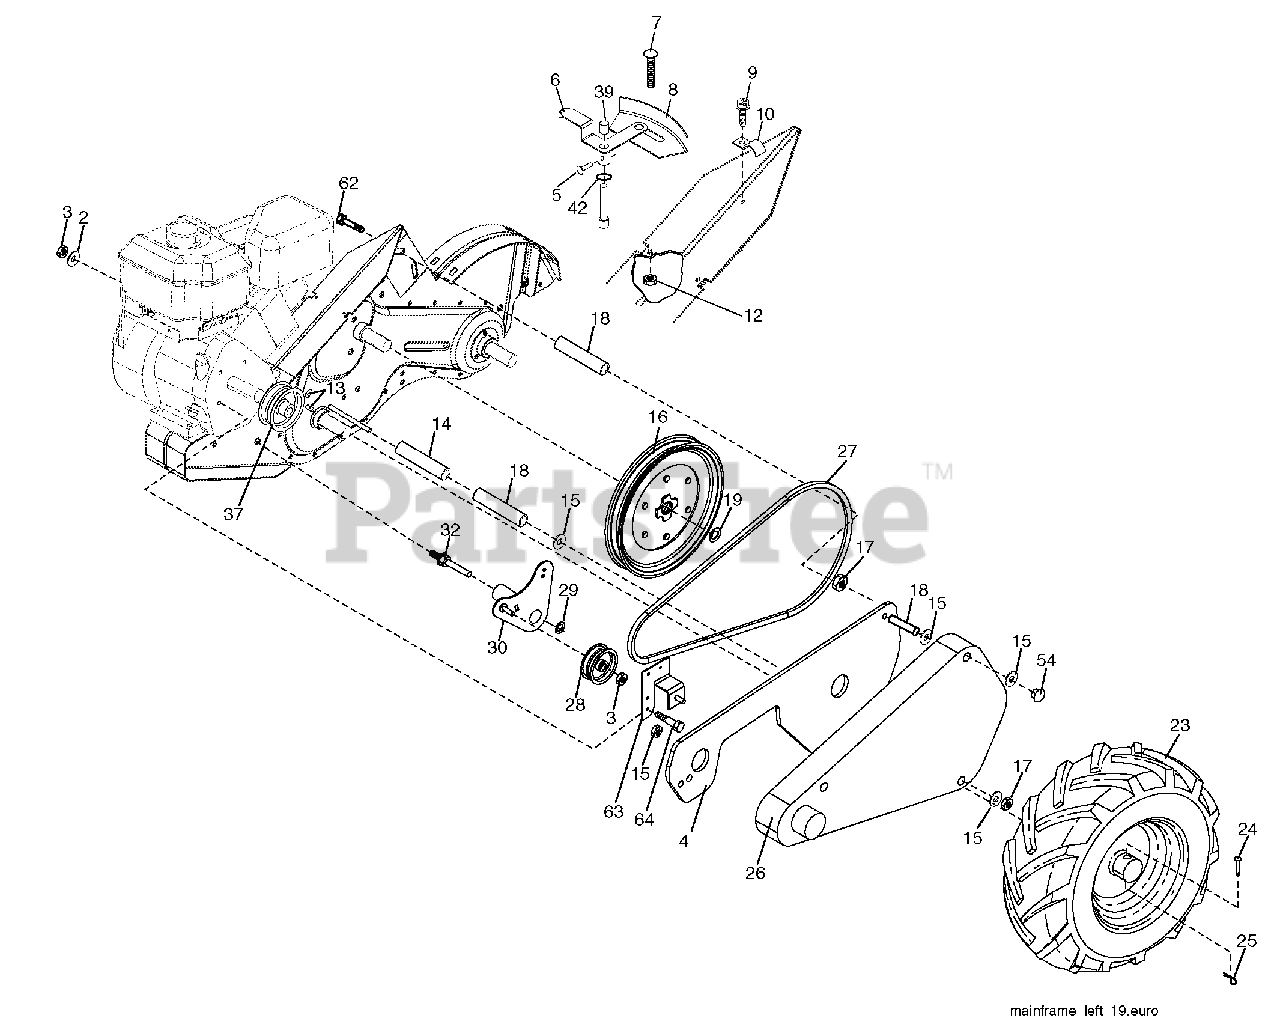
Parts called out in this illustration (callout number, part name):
2	Washer, Lock 3/8
3	Nut, Hex 3/8-16
4	Shield, Inner Belt Guard RT
5	Pin Spirol Flared
6	Lever, Shift
7	Bolt, Carriage 1/4-20 x 1/2 Gr. 5
8	Plate, Shift Indicator
9	Screw, Hex, Washer Head, Slotted #10-24 x 1/2
12	Nut, Keps Hex 1/4-20 unc
13	Screw, Set, Hex 5/16-18 x 3/8
14	Spacer, Split 0.327 x 0.42 x 1.220
15	Washer 11/32 x 11/16 x 16 Ga.
16	Sheave, Transmission
17	Nut Hex 5/16-18
18	Spacer Split
19	Ring, Retainer
24	Rivet, Drilled
25	Clip, Hairpin
26	Guard, Belt
28	Pulley, Idler
29	Ring, Klip
30	Bracket, Idler
32	Shaft, Idler Arm
37	Sheave, Engine
39	Cap Plunger
54	Nut 5/16-18
62	Bolt Hex 5/16-18 x 4-1/2
63	Bracket Asm Guard
64	Bolt Fin 5/16-24 unf x 1/2
